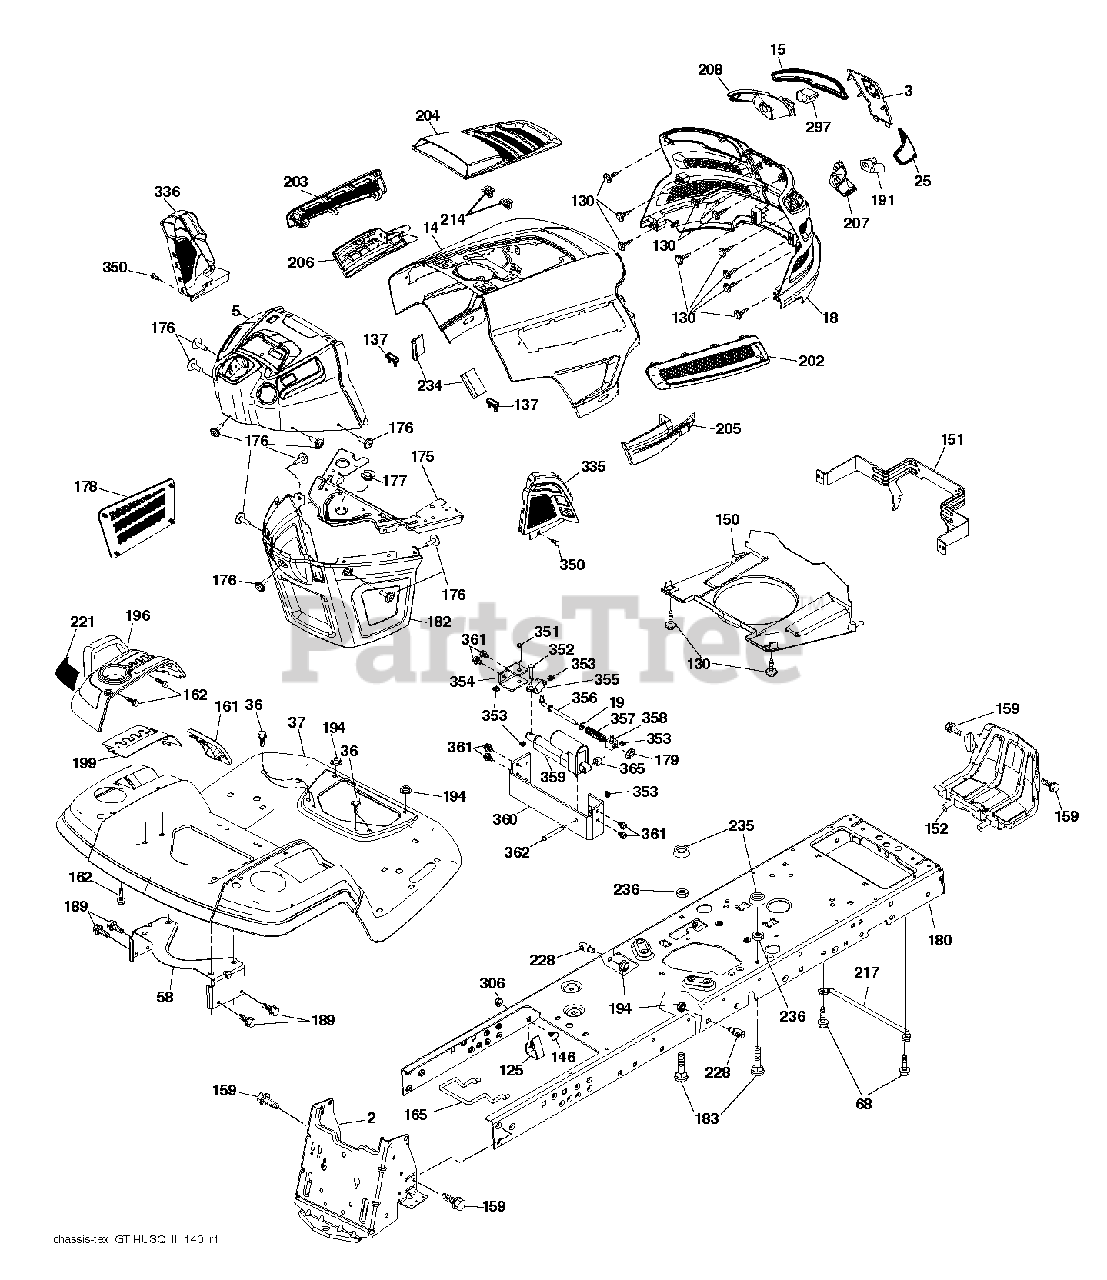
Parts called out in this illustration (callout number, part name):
2	DRAWBAR.STGT
3	APPLIQUE.SUBASM.GT.HUSQ.II
5	DASH.UPR.ASM.GT2.SRV.MIN.PTO
14	HOOD.ASM.HUSQVARNA.GT.TEX.ORAN
15	LENS.HEADLIGHT.LH.GTII.2011
18	GRILLE.SUBSTRATE.2011.
19	WASHER
25	LENS.HEADLIGHT.RH.GTII.2011
36	SCREW 5/16"
37	FENDER.PNT.TX.GT.CH/FW/DL.HUSQ
58	BRKT.SUPPORT.FNDR/TANK
68	SCREW LT
125	CLIP.FUEL.LINE
130	SCREW.#10 X 0.750.BOS
137	BUMPER DASH
146	BOLT.RDHD.SHT.SQNK.3/8-16X5/8
150	AIR.DUCT.GTV.BLACK
151	BRACKET.PIVOT.HOOD.GT.HUSQ.II
152	SHIELD.BROWNING.PNT.GT.V2
159	SCREW, 3/8-16X3/4
161	CONSOLE.WINDOW.FUEL.HUSQ.GT
162	SCREW.HI-LO.CONSOLE
165	SUPPORT.TANK.REAR.B/TE
175	PLATE.CROSSMEMBER.HUSQ
176	SCREW.#10-24X5/8.RN.QU
177	BUSHING, STEERING
178	CARGO.ASM.NET.TXGT.W/C
180	CHASSIS.TEX.BOLTED
182	DASH.LOWER.COMMON.12V.ADAPTOR
183	BOLT.5/16-18X1-1/4 FULL THD
189	SCREW
191	INSERT.REFLECTIVE.RH.HUSQ.GTII
194	NUT LOCK HEX FLANGE 5/16-18
196	CONSOLE.ASM.DECKLIFT.HUSQGT.DL
199	PLATE.DECK.LIFT.HUSQVARNA.GT
202	VENT.SIDE.RH.GT.HUSQ.II.
203	VENT.SIDE.LH.GT.HUSQ.II.498
204	VENT.TOP.HUSQ.GT2
205	SIDE.TRIM.RH.GT.HUSQ.II
206	SIDE.TRIM.LH.GT.HUSQ.II.GRAY
207	BEZEL LIGHT.RH.GT.II.MYLAR
208	BEZEL LIGHT.LH.GT.II.MYLAR
214	CLIP.RETAINER.TINNER.
217	ROD.PIVOT.HOOD
221	REFLECTOR.LH.TEX GT HU
228	STUD.FASTNER.W/ANTI-ROTATE
234	BUMPER.HOOD.TEX.HUSQVARNA
235	SPACER FENDER
236	NUT.CENTERLOCK.5/16-
297	INSERT.REFLECTIVE.LH.HUSQ.GTII
306	NUT LOCK FLG 3/8-16 UNC
335	COVER.LOWER.DASH.RH.BLACK
336	COVER-LH.LOWER.DASH.GT2.BLACK
350	CLIP.X-MAS.TREE
351	PIN.CLEVIS.375X2.125
352	PIN.CLEVIS.(.375 X 1.25)
353	CLIP RETAINER
354	SUPPORT.BELLCRANK
355	BELLCRANK.PIVOT.LOCK.DIFF
356	LINK.LOCK.DIFF
357	SPRING.COMPRESSION
358	GUIDE.SWIVEL
359	ACTUATOR.ELECTRIC
360	BRACKET.ACUATOR
361	SCREW LT.3/8-46X5/8
362	PIN.CLEVIS.(.375 X 2.42)
365	SPACER.NYLON.75" X .4375
